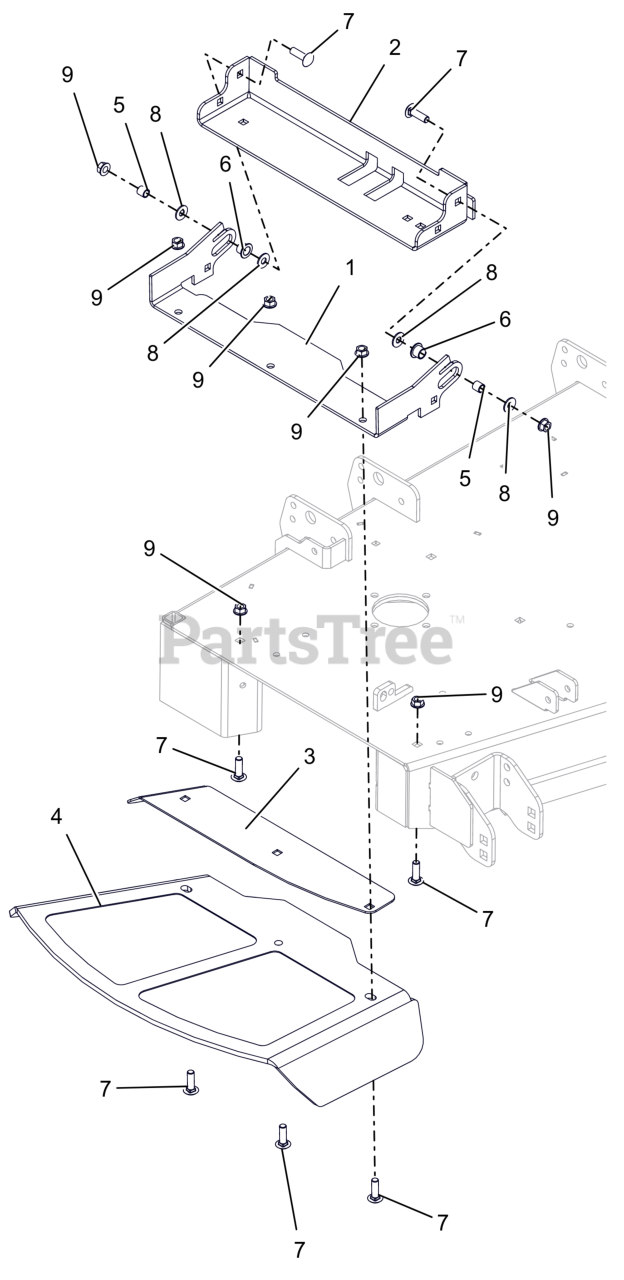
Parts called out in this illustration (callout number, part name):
1	BRKT, CHUTE MOUNT (RED)
2	BASE, DISCHARGE CHUTE MTG BRKT (RED)
3	48-60 DISCH CHUTE CLMP PLT-RED
4	CHUTE, FORMED RUBBER DISCHARGE
5	SPCR, .385X.500X.350
6	BSHG, FLANGED .50X.625X.50X.062
7	BLT,RHSSN .38-16X1.25 G5 ZCC
8	WSHR, HDND 0.375X0.875X0.064 ZCC
9	NUT-LK-CTR-FLG .375-16 GF ZCC
